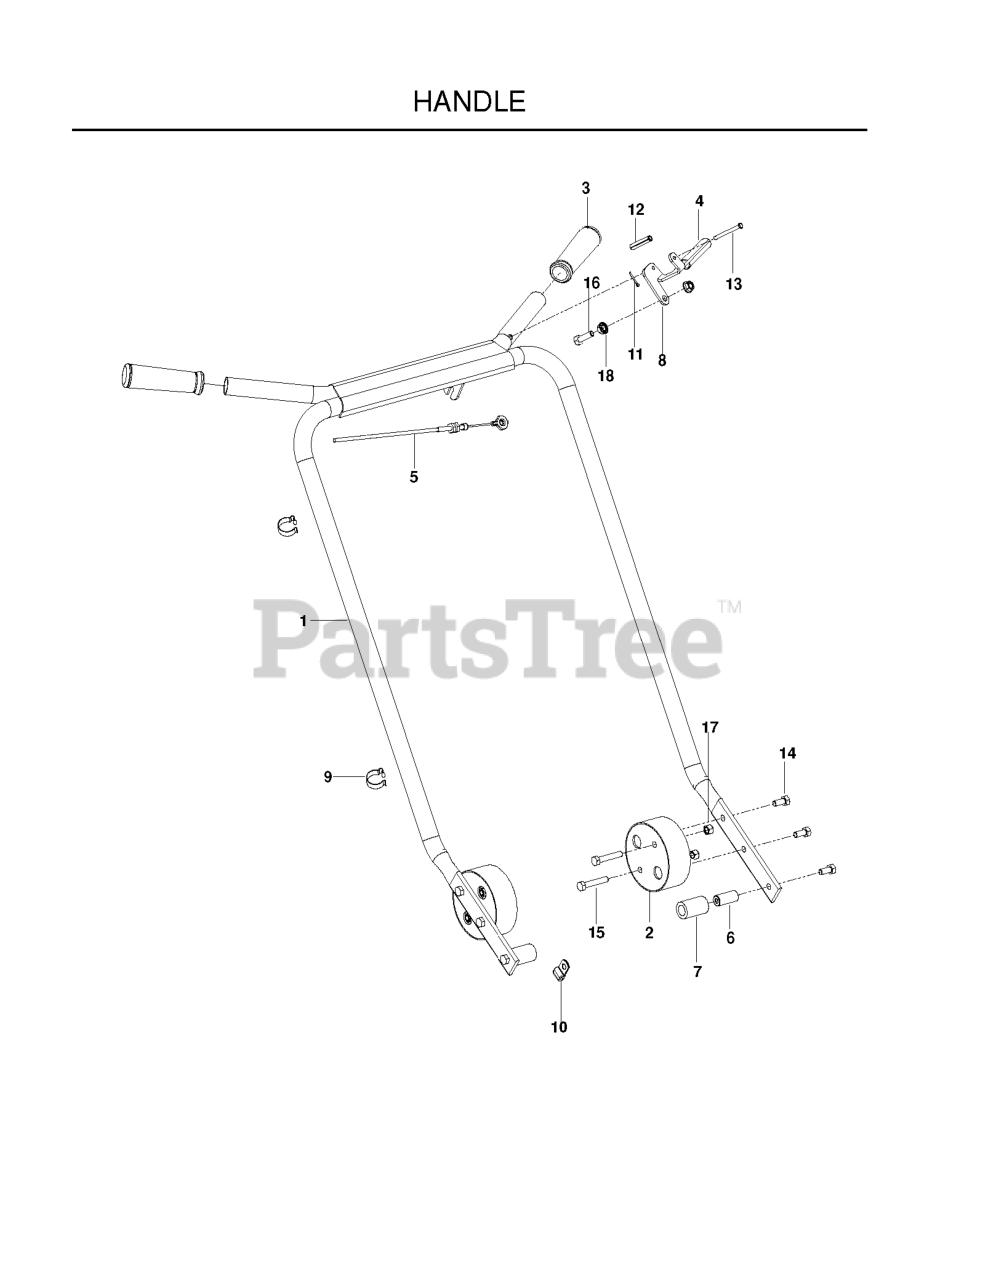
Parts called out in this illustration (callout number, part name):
1	HANDLE - GREY
2	MOUNT, VIBRATION
3	GRIP, HANDLE 1" ID BLACK
5	CABLE - PULL
7	BUSHING, POLYURETHANE
8	LEVER - THROTTLE, ORANGE
9	CLIP - CABLE
10	DOUBLE TUBE CLAMP
11	COTTER PIN 3/32 X 3/4
12	5/16" DIA ROLL PIN X 1.5
13	PIN, CLEVIS
14	HCS M8-1.25 X 22MM GR 8.8 ZD
15	HCS 5/16C X 1 3/4
16	HCS 5/16C X 1
17	NUT 5/16 NYLOC
18	NUT 5/16C WHIZ
